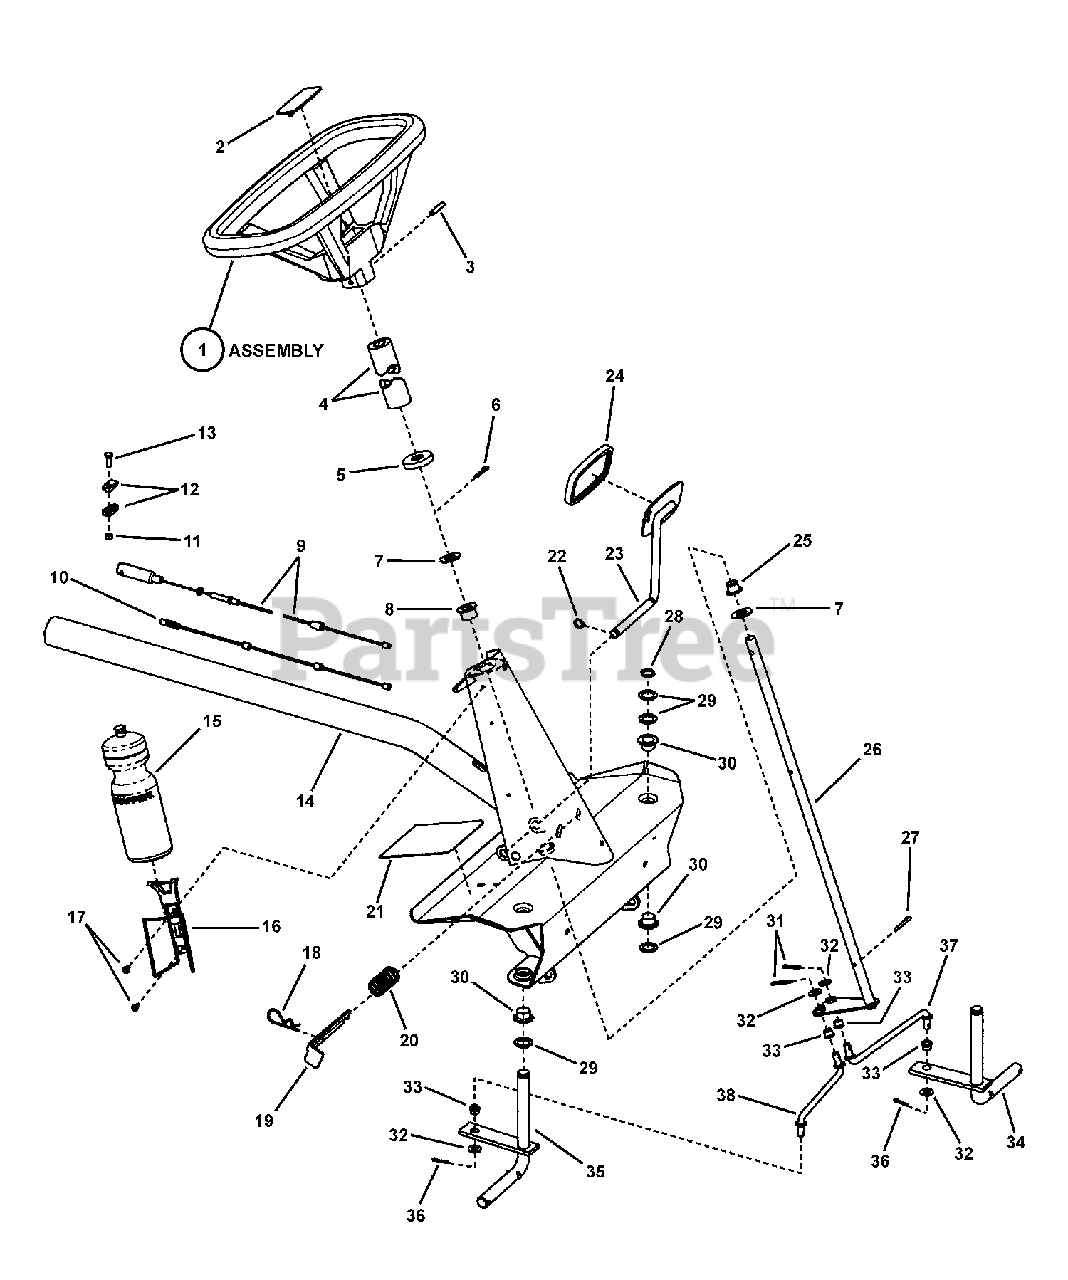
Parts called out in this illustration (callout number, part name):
1	ASSEMBLY, Steering Wheel (for 5/8" shaft)
2	LOGO, Steering Wheel
3	ROLL PIN, 1/4 x 1-1/2"
4	FOAM COVER, Steering Shaft
5	COVER, Steering Shaft
6	PIN, 3/16 x 1" Cotter
7	WASHER, .66 x 1.31 x .09 Flat
8	BUSHING, Nylon
9	CABLE, Brake, Snap-In
10	CABLE, Clutch/Brake (54.32" long)
10	CABLE, Clutch/Brake (55" long)
11	NUT, 1/4-20 Hex Center Lock, GR 5 or B
12	CONNECTOR, Cable
13	SCREW, 1/4-20 x 3/4" Hex Head Cap, GR 5
14	WELDMENT, Front Axle, Narrow
14	WELDMENT, Front Axle, Wide
15	BOTTLE, Water
16	HOLDER, Bottle (Wire)
17	SCREW, #10-24 x 1/2" Hex Washer Self-Tap (Torx)
18	HAIR PIN 2-1/4"
19	LATCH, Parking Brake
20	SPRING, Parking Brake Latch
21	FOOT PAD, Short (5.5" x 4.7")
21	FOOT PAD, Long (5.5" x 9.5")
22	RING, 1/2" External Retaining (Heavy Duty)
23	WELDMENT, Clutch Pedal
24	PAD, Pedal
25	BUSHING, Nylon
26	WELDMENT, Steering Shaft
27	PIN, 3/16 x 1-1/2" Cotter
28	RING, 5/8" External Retaining
29	WASHER, .77 x 1.13 x .06 Flat
30	BEARING, Nylon
31	PIN, 5/32 x 1" Cotter
32	WASHER, 3/8" Flat SAE
33	BUSHING, Tie Rod
34	WELDMENT, King Pin, Left Hand
35	WELDMENT, King Pin, Right Hand
36	PIN, 1/8 x 3/4" Cotter
37	TIE ROD, Left Hand (7.41" long)
37	TIE ROD, Left Hand (9.91" long)
38	TIE ROD, Right Hand (7.41" long)
38	TIE ROD, Right Hand (9.91" long)
